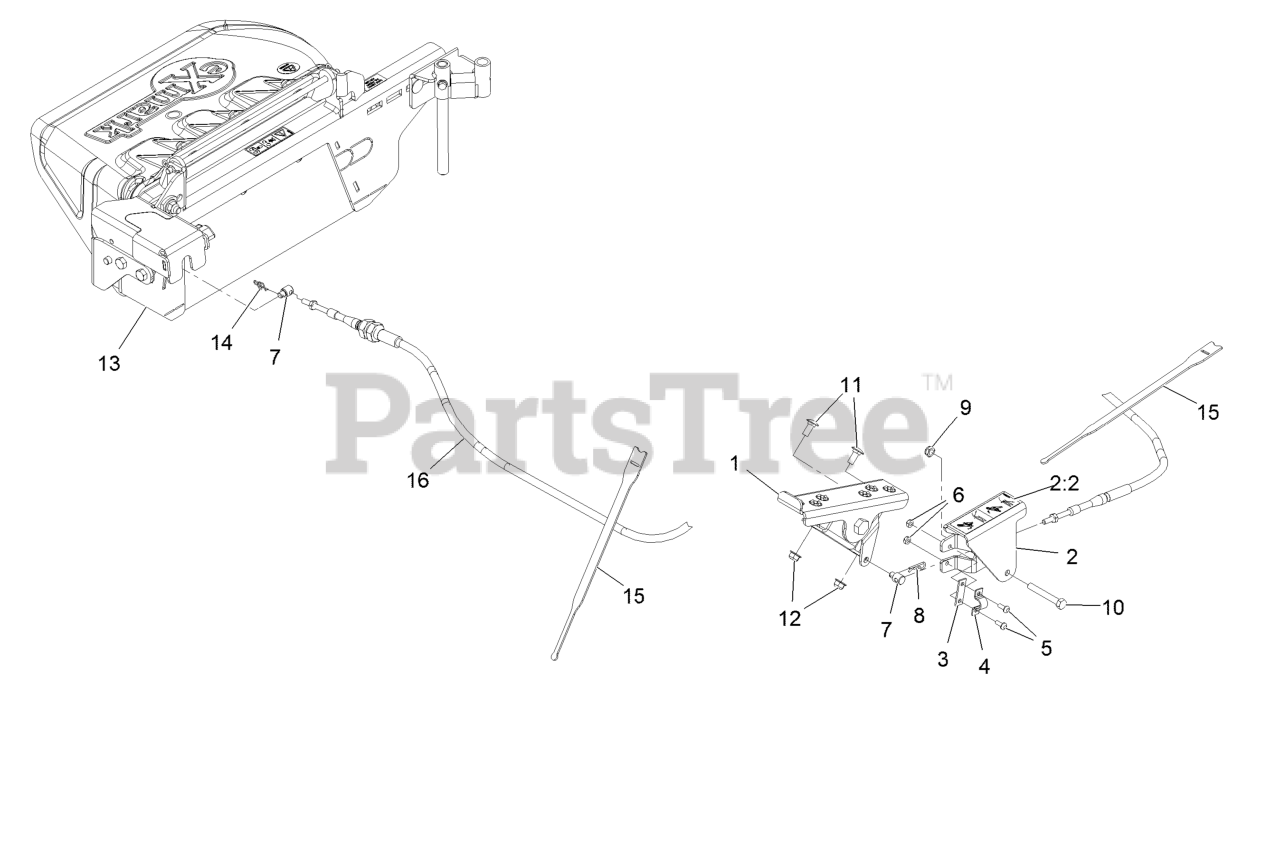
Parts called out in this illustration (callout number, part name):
1	ASM, Pedal, Ocd Gate
2	Assembly, Cable Bracket
2:2	Decal-Ocd Operation
3	Shim,Control Cable
5	Screw-HSBH
6	Nut-Nyloc #10-24 Thin
7	Pivot, Control Cable
8	Hairpin-Cotter
9	Nut-Nyloc 5/16-18 Thin
10	Screw-HH 5/16-18 X 2 1/4
11	Bolt-Carriage 5/16-18 X 3/4 Short Neck
12	Nut-Nyloc 5/16-18 Flg
13	ASM, Ocd
14	Pin-Cotter, Locking
15	Strap-Velcro, Cable Tie
16	Cable-Discharge Gate
